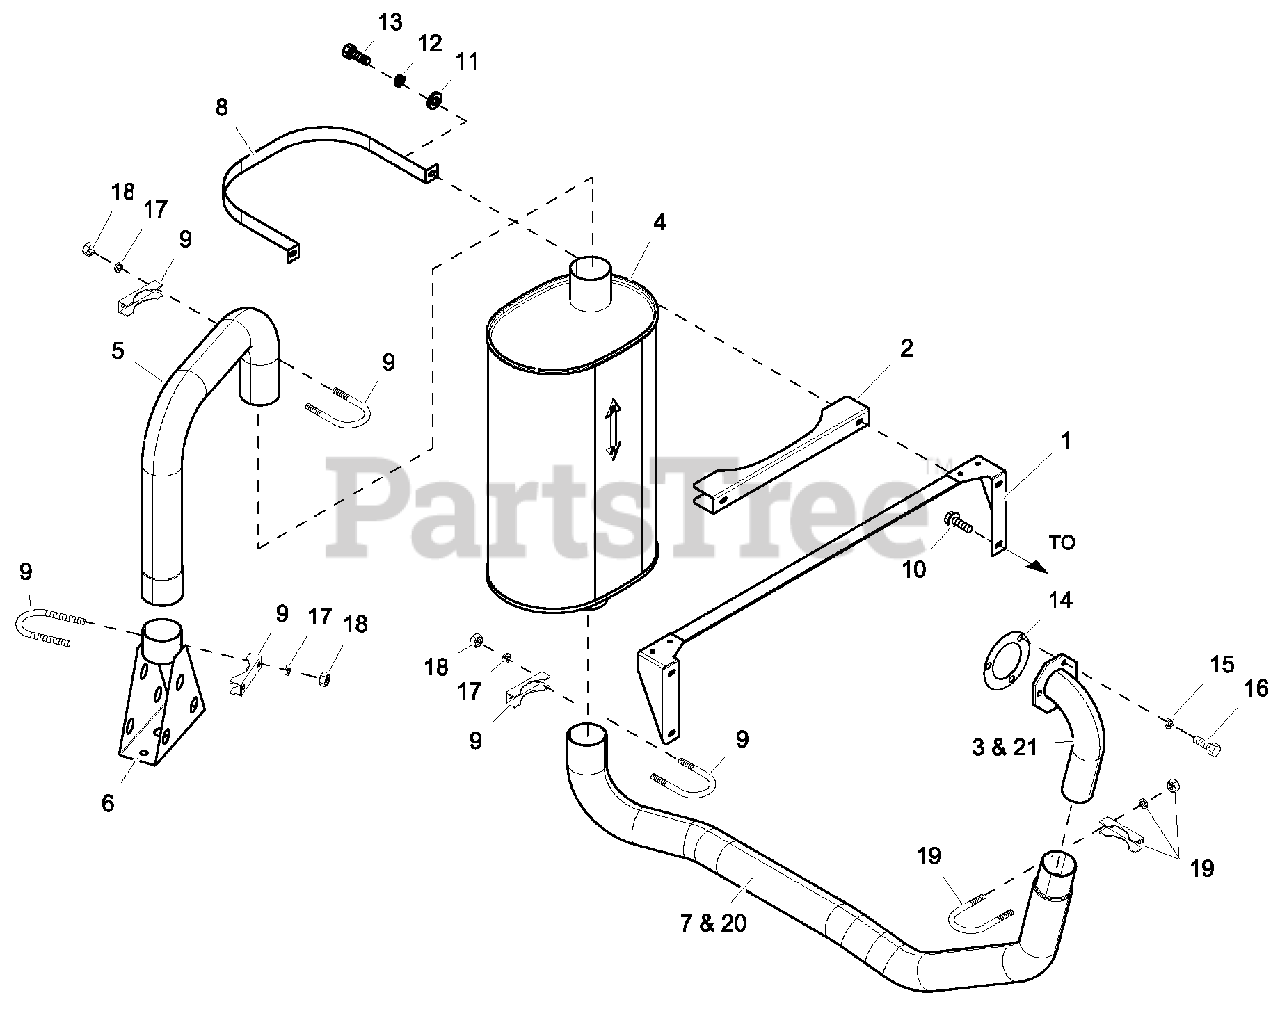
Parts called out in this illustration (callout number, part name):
1	BRACKET MUFFLER
2	BRACKET STIFFENER
3	UPPER EXHAUST PIPE ASM
4	MUFFLER 60kW
5	EXHAUST PIPE
6	DIFFUSER EXHAUST WEL DMENT
7	EXHAUST PIPE
8	STRAP MUFFLER
9	BOLT U 3/8-16X2.62
10	SCREW THF M6-1 X 16 N WA Z/JS
11	WASHER FLAT 1/4-M6 ZINC
12	WASHER LOCK M6-1/4
13	SCREW HHC M6-1.0 X 35 G8.8 BLK
14	GASKET TURBO/EXHAUST 2.4L 36KW
15	WASHER LOCK M8 SS
16	SCREW HHC M8-1.25 X 25 SS
17	WASHER LOCK 3/8
18	NUT HEX 3/8-16 STEEL
19	BOLT U 3/8-16 X 2.30 W/SADDLE
